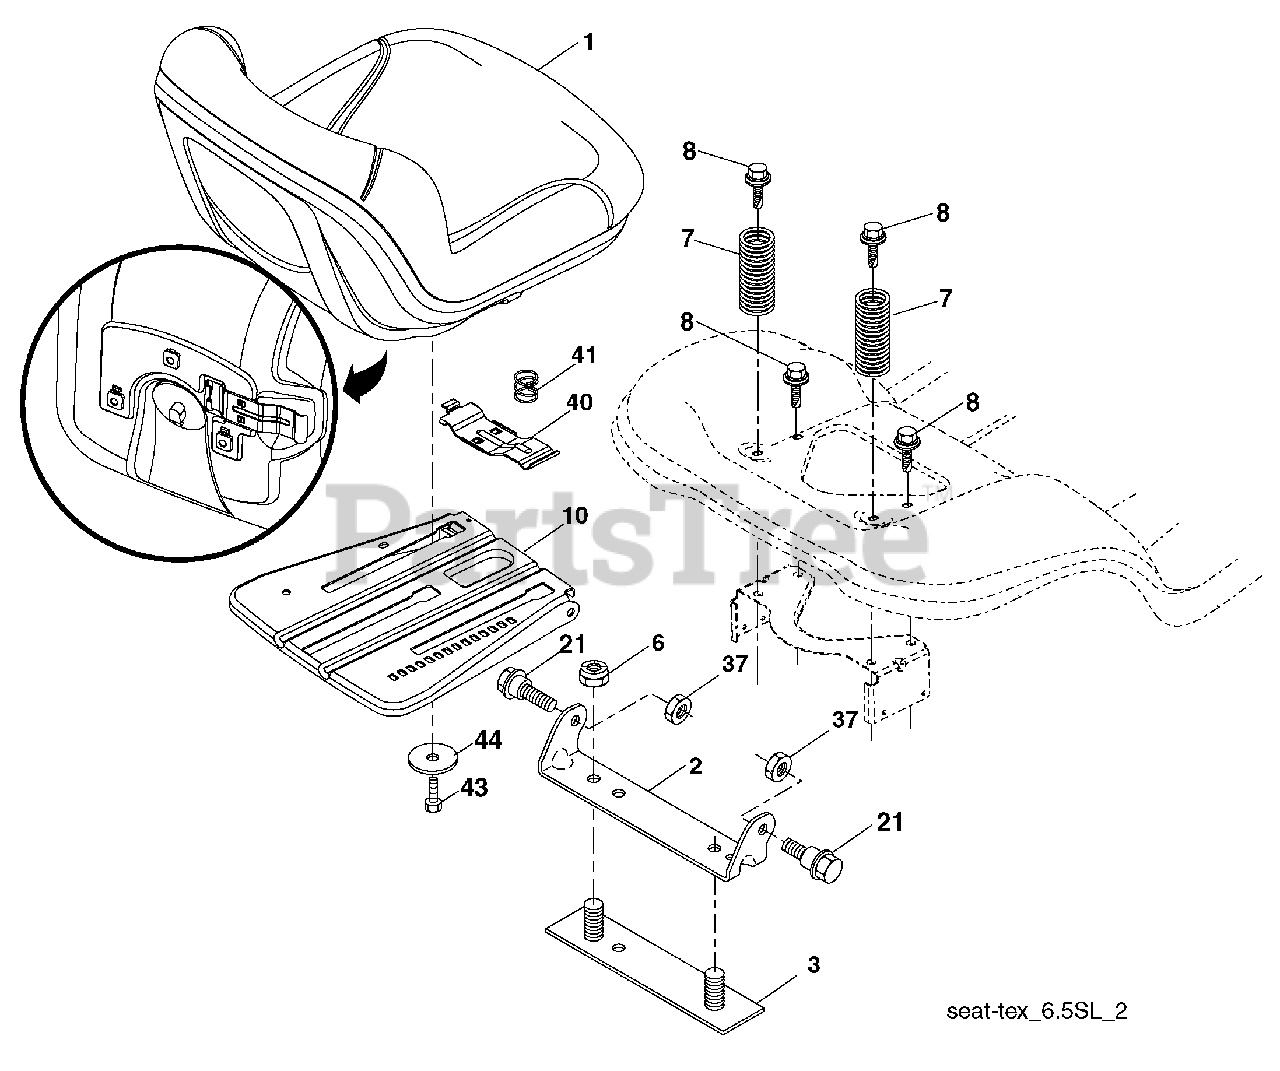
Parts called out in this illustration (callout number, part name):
1	Seat
2	Bracket Pivot Fender
3	Strap, Asm Fender
6	Nut, Lock W/Ins. 3/8-16 unc
7	Spring, Seat Cprsn
8	Bolt 5/16-18 unc x 3/4 w/Sems
10	Pan, Seat
21	Bolt, Shoulder 5/16-18
37	Nut, Lock 5/16-18 unc
40	Handle Slide Seat
41	Spring Latch Seat
43	Bolt Fin Hex 3/8-16 unc x 3/4
44	Washer 13/32 x 2-3/8 x 12 Ga.
